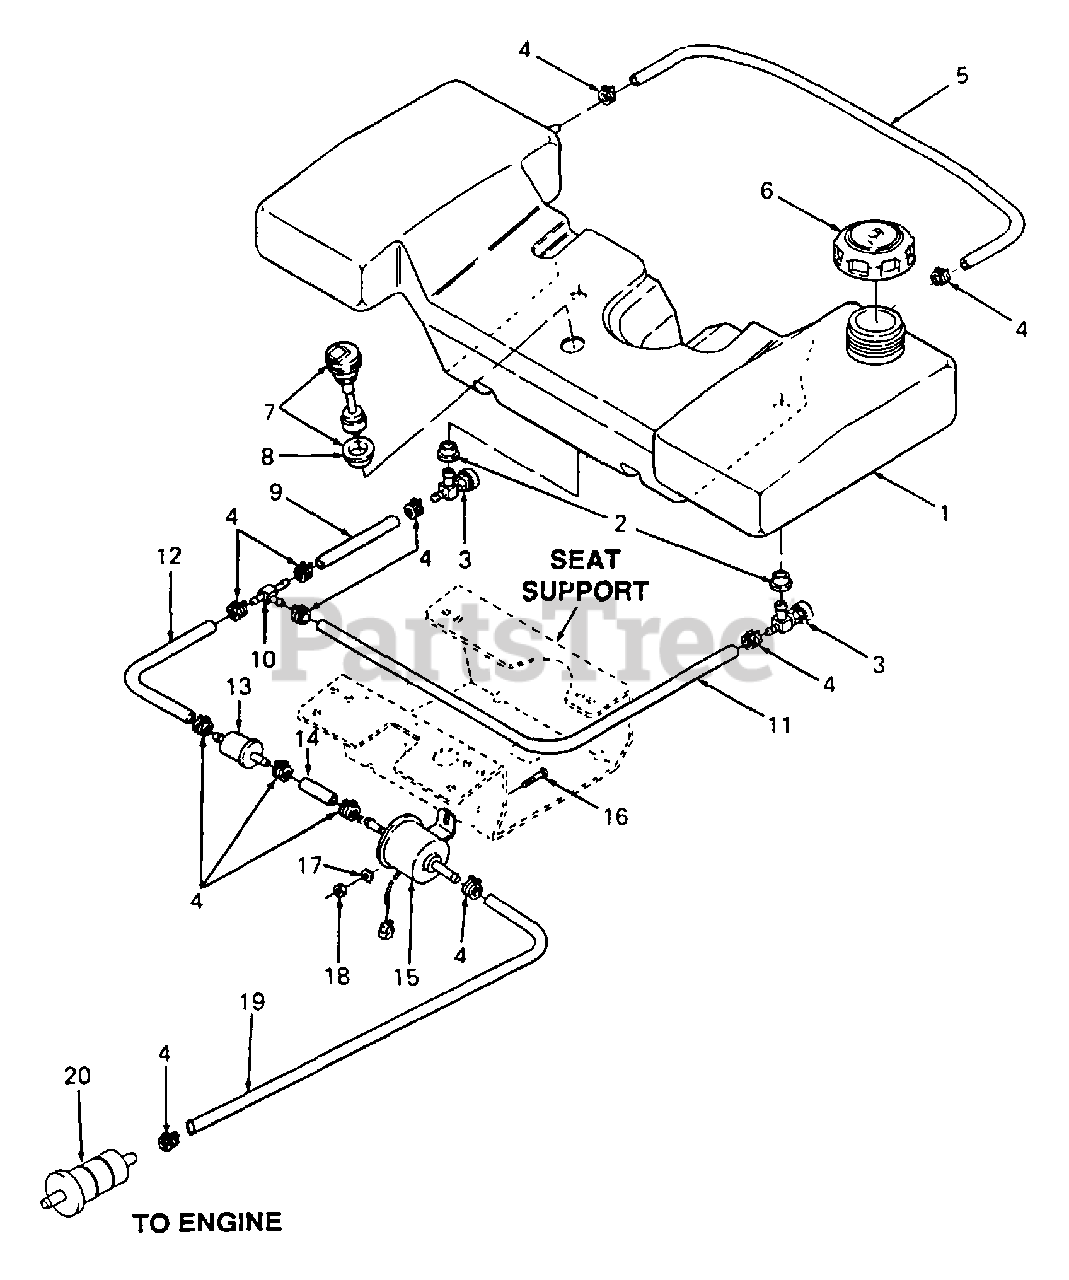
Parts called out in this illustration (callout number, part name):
1	Tank, Fuel
2	Bushing
3	Valve, Fuel Shutoff
4	Clamp, Hose
5	Line, Fuel - 24" Lg
6	Cap, Fuel
7	Sensor, Low Fuel
8	Bushing, Rubber
9	Line, Fuel - 5" Lg
10	T-Fitting
11	Line, Fuel - 17" Lg
12	Line, Fuel - 6" Lg
13	Filter, Fuel
14	Line, Fuel - 2" Lg
15	Fuel Pump Assy
16	Screw, Truss Mach, 1/4-20 x .62 Lg
17	Washer, Spring, .265 x .562
18	Nut, Hex Flange Lock, 1/4-20
19	Line, Fuel - 64" Lg
20	Filter, Fuel
